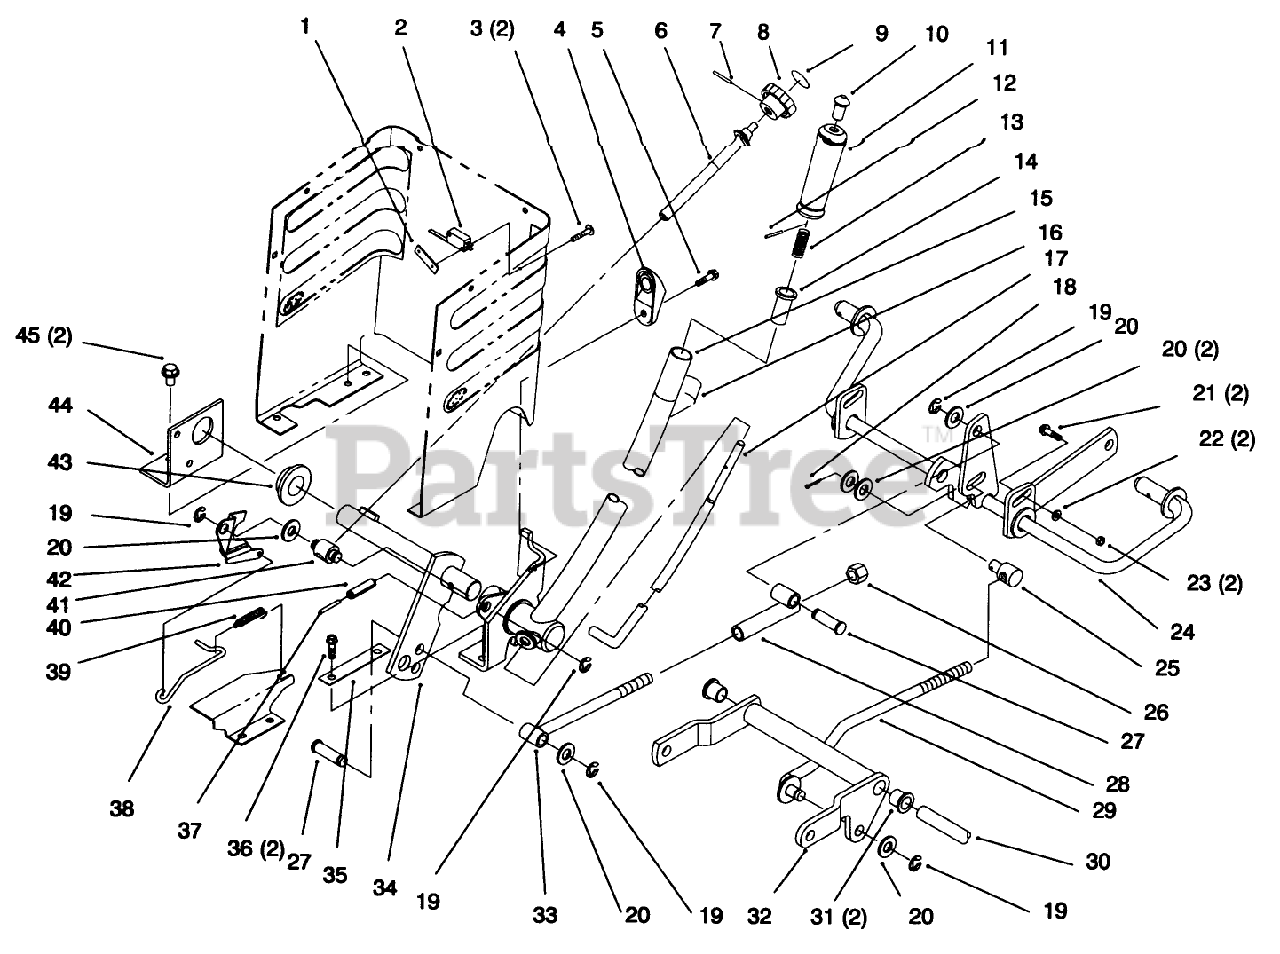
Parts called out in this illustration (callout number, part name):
1	NUT-SPEED
2	SWITCH-MICRO
4	WEDGE - HOC
5	SCREW-HWH
7	PIN-SPIROL
10	TIP-ROD
11	GRIP-HANDLE
12	PIN-SPIROL
13	SPRING-COMPRESSION
14	RETAINER-SPRING
15	LEVER-LIFT
16	DECAL-LIFT
17	ROD-LEVER, LIFT
18	PIN-COTTER
19	RING-RETAINING, EXTERNAL
20	WASHER-FLAT
21	BOLT-CARR
22	WASHER-FLAT
23	NUT-LOCK, NI
24	SHAFT-GAGE
26	NUT-LOCK, NI
31	BUSHING-FLANGE
32	ARM-PIVOT
34	SHAFT-LIFT
36	SCREW-HWHTF
37	PIN-SPRING
38	ROD - HOC INDICATOR
39	SPRING - EXTENSION
40	PIN-ROLL
42	PLATE - HOC GAGE
43	BEARING-FLANGE
44	BRACKET-PIVOT, LINKAGE
45	SCREW-HWHTF
